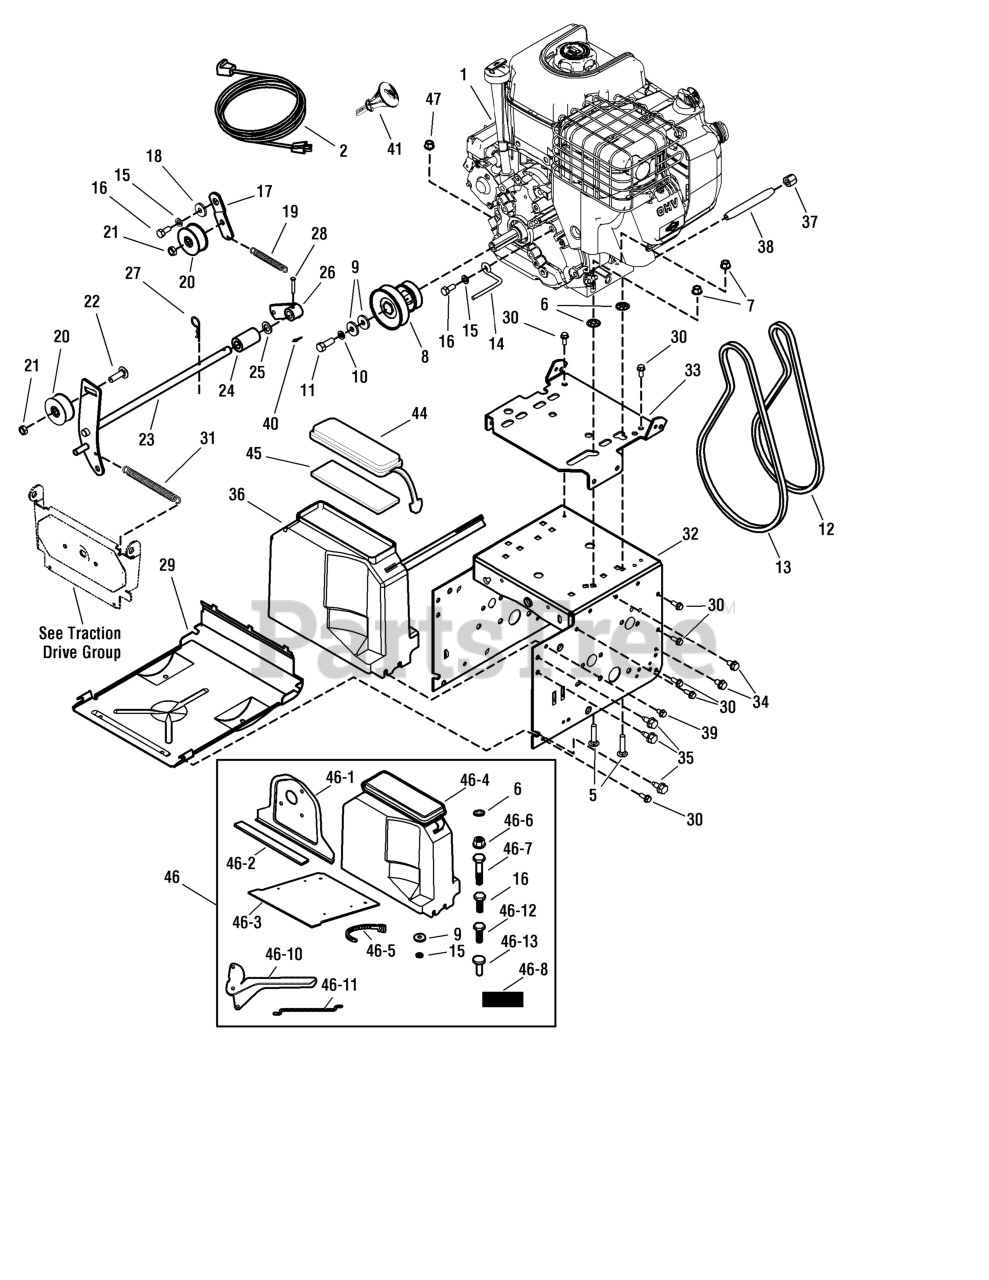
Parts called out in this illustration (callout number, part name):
1	ENGINE
2	CORD, Electric, 10FT. 110V
5	BOLT, Carriage, 5/16-18 x 1-1/2q
6	NUT, Speed, 1/4
7	NUT, Hex Flange Nylock, 5/16-18
8	PULLEY, Engine
9	WASHER, Flat, 3/8
10	WASHER, Locking, 3/8
11	CAPSCREW, Hex-Head, 3/8-24 x 1-1/4
12	V-BELT, Drive, 3L
13	V-Belt, Auger, 4L
14	GUIDE, Belt
15	WASHER, Locking, 5/16
16	BOLT, Hex-Head, 5/16-24 x 3/4
17	ASSEMBLY, Idler Bracket
18	BUSHING, Idler Bracket
19	SPRING, Extension
20	IDLER, Plastic, Ball Bearing
21	NUT, Hex-Jam, 3/8-16
22	BOLT, Carriage, 3/8-16 x 1-1/4
23	IDLER, Auger Assembly
24	SPACER, Auger Idler
25	WASHER, Flat, 1/2
26	ASSEMBLY, Spring Attachment
27	PIN, Hair
28	PIN, Clevis
29	PANEL, Bottom
30	SCREW, 1/4-20 x 5/8
31	SPRING, Extension
32	FRAME, Steerable
33	ENGINE MOUNT
34	SCREW, 3/8-18 x 1/2
35	SCREW, 3/8-18 x 3/4
36	COVER, Belt
37	CAP, Pipe
38	PIPE, Oil Drain
39	SCREW, Hex-Washer, 1/4 x 3/4, Self-Tapping
40	PIN, Cotter, 1/4, Self-Locking
41	KEY, Ignition
44	LID, Toolbox
45	PAD, Foam
46	KIT, Drive Seal
46-1	SEAL PLATE
46-2	SEAL STRIP
46-3	SEAL, Engine Plate
46-4	BELT COVER
46-5	TIE, Self Locking
46-6	NUT, Hex Flange Two-Way Lock, 5/16-18
46-7	SCREW, 5/16-24 x 1.00
46-8	DECAL, Hinge
46-10	CLUTCH LEVER
46-11	ROD, Hold down
46-12	CAPSCREW, Hex Head 1/4-20 x 1-3/4 G5
46-13	SPACER, 1/4 ID x 3/8 OD 1" Long
47	NUT, Hex Flange, 5/16-18 Whiz Lock Small
